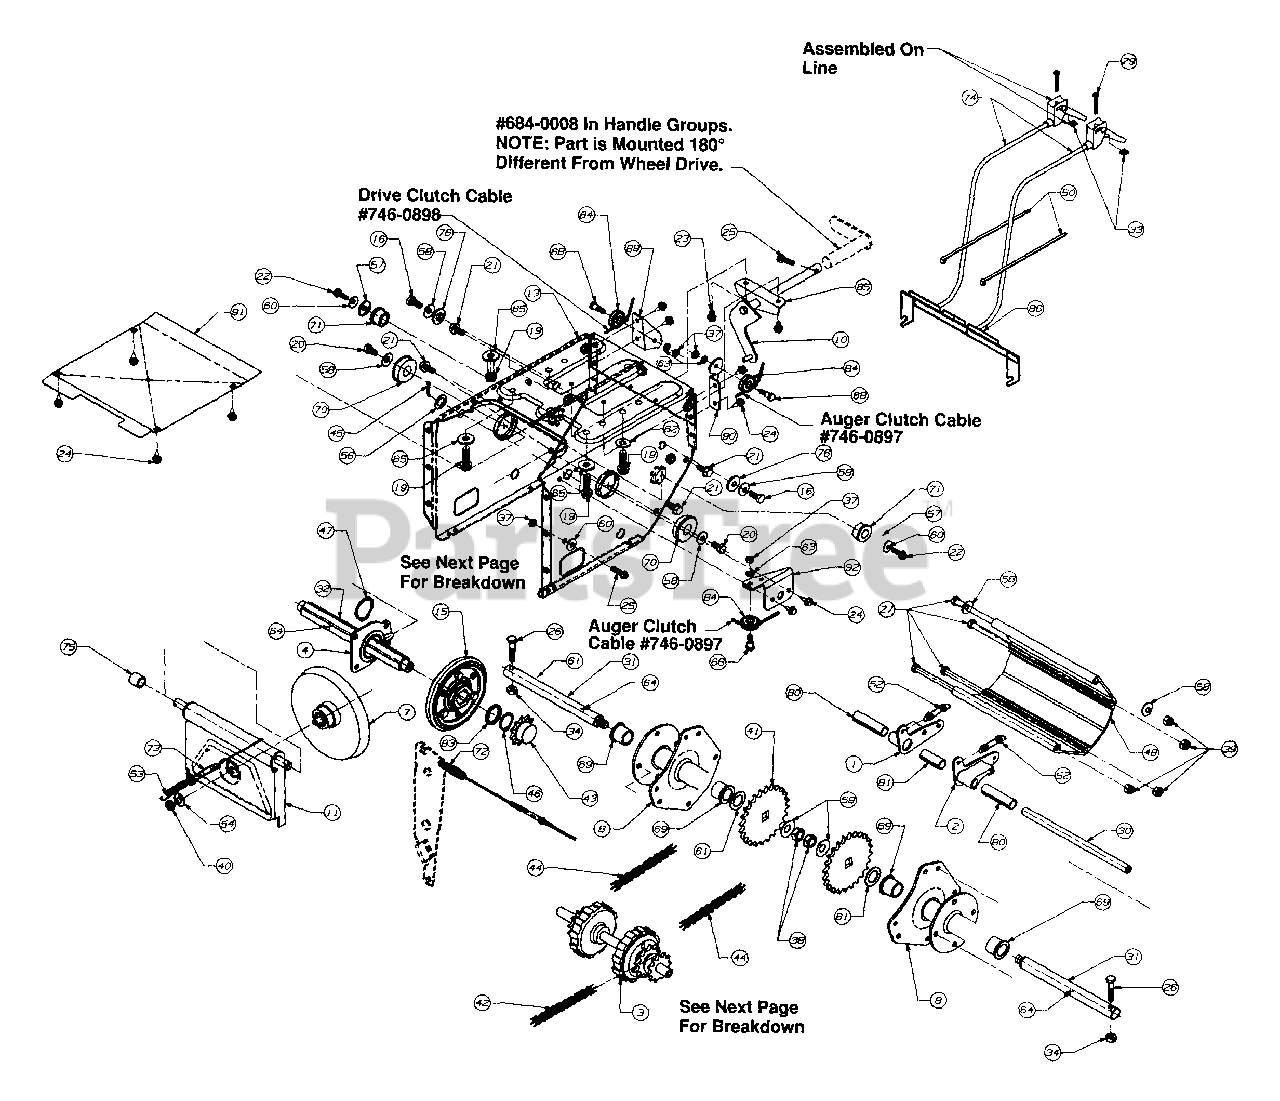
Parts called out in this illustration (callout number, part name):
1	Dog Assembly, R.H.
2	Dog Assembly, L.H.
3	Drive Shaft Assembly
4	Bearing Friction Wheel
7	Friction Wheel Disc
10	Rod Shift, Track Drive
15	Wheel Friction
16	Hex Cap Screw
19	Hex Self-Tap Screw
20	Hex Self-Tap Screw
21	Screw, Hex
22	Screw, Hex
23	Screw, Hex
24	Hex, Screw
25	Screw, Hex
26	Screw, Hex
27	Screw, Hex
29	Scr., Oval
31	Axle, Drive
33	Nut, Flange
34	Nut, Hex Lock
37	Nut, Hex Jam
38	Hex Ins. Jam
39	Hex L-Nut
40	Jam Nut, Hex
42	Chain, Endless
43	Drive Sprocket
44	Chain, Endless
45	Pin, Cotter
46	Ring, Snap
47	Ring, Retainer
48	Housing, Track
50	Cable Tie
52	Spring
53	Extension Spring
56	Washer, Flat
57	Washer, Flat
58	Washer, Bell
59	Washer, Bell
60	Washer, Bell
61	Washer, Flat
62	Washer, Flat
63	Washer, Lock
64	Washer, Flat
65	Washer, Flat
68	Shoulder Screw
69	Bearing, Flange
70	Bearing, Ball, With Snap Ring
71	Bearing, Flange
72	Cable, Auger
73	Cable, Clutch
74	Cable, Track Steer w/Trigger
76	Shoulder Spacer
80	Spacer, Split
81	Spacer, Split
83	Spacer
84	Roller, Cable
